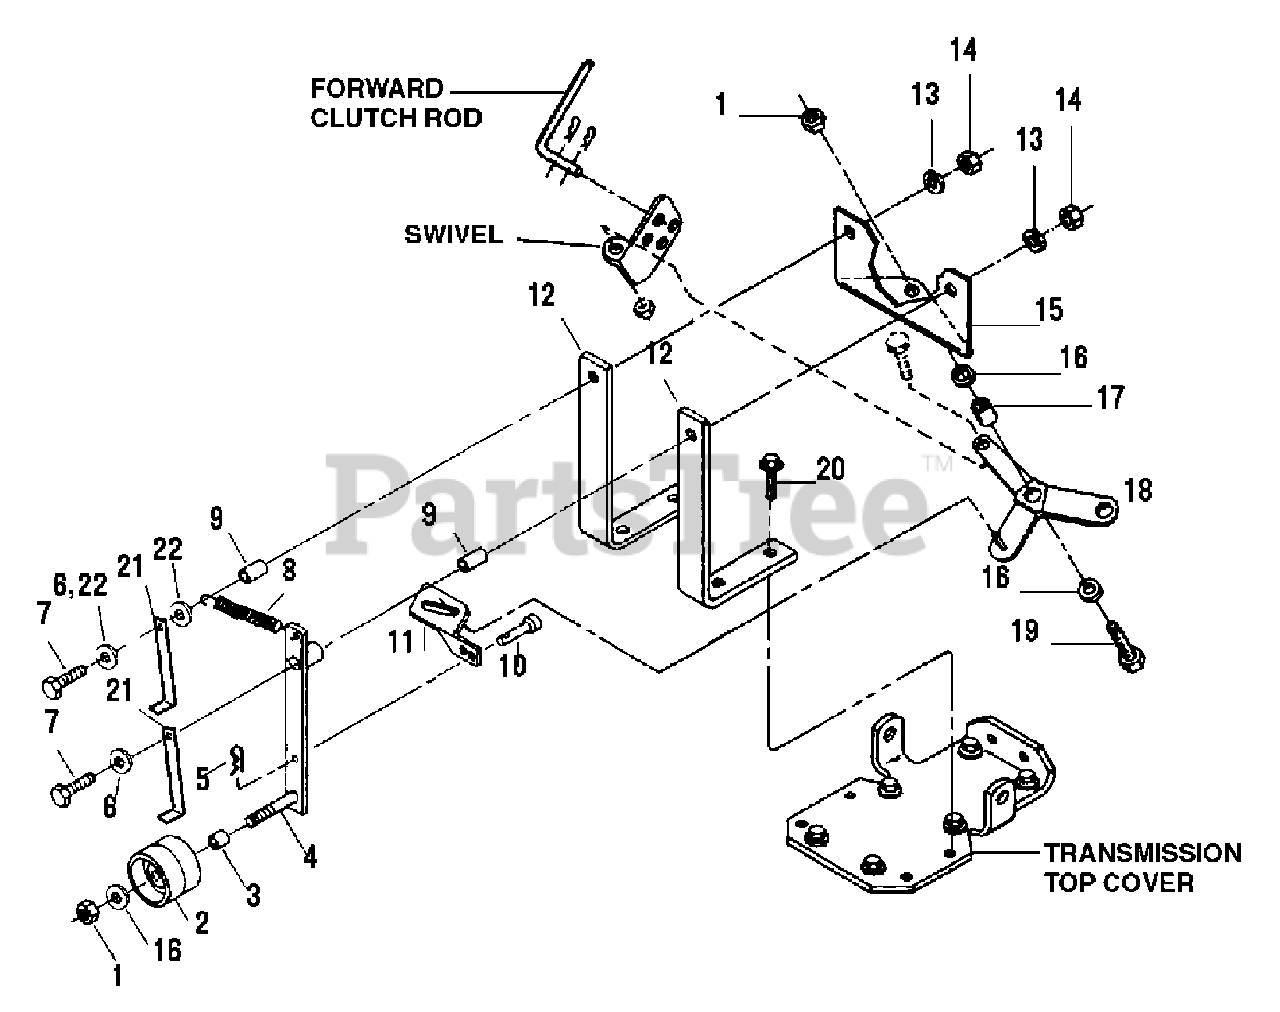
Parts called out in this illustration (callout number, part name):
1	Hex Locknut, 3/8-16
2	Idler Pulley, Forward
3	Spacer
4	Left Idler Arm, forward tiller direction
5	Hairpin Cotter
6	Plain Washer, 5/16
7	Hex Hd. Screw, 5/16-18 x 2-1/4
8	Spring
9	Pivot Bushing
10	Pin
11	Forward Link
12	Mounting Bar
13	Lockwasher, 5/16
14	Hex Nut, 5/16-18
15	Shifting Base
16	Spacer (Bushing)
17	Bushing (Bellcrank)
19	Hex Hd. Screw, 3/8-16 x 1-1/4
20	Hex Flange Screw, 5/16-18 x 1
21	Belt Guide, Forward Belt
22	Flat Washer, 5/16
